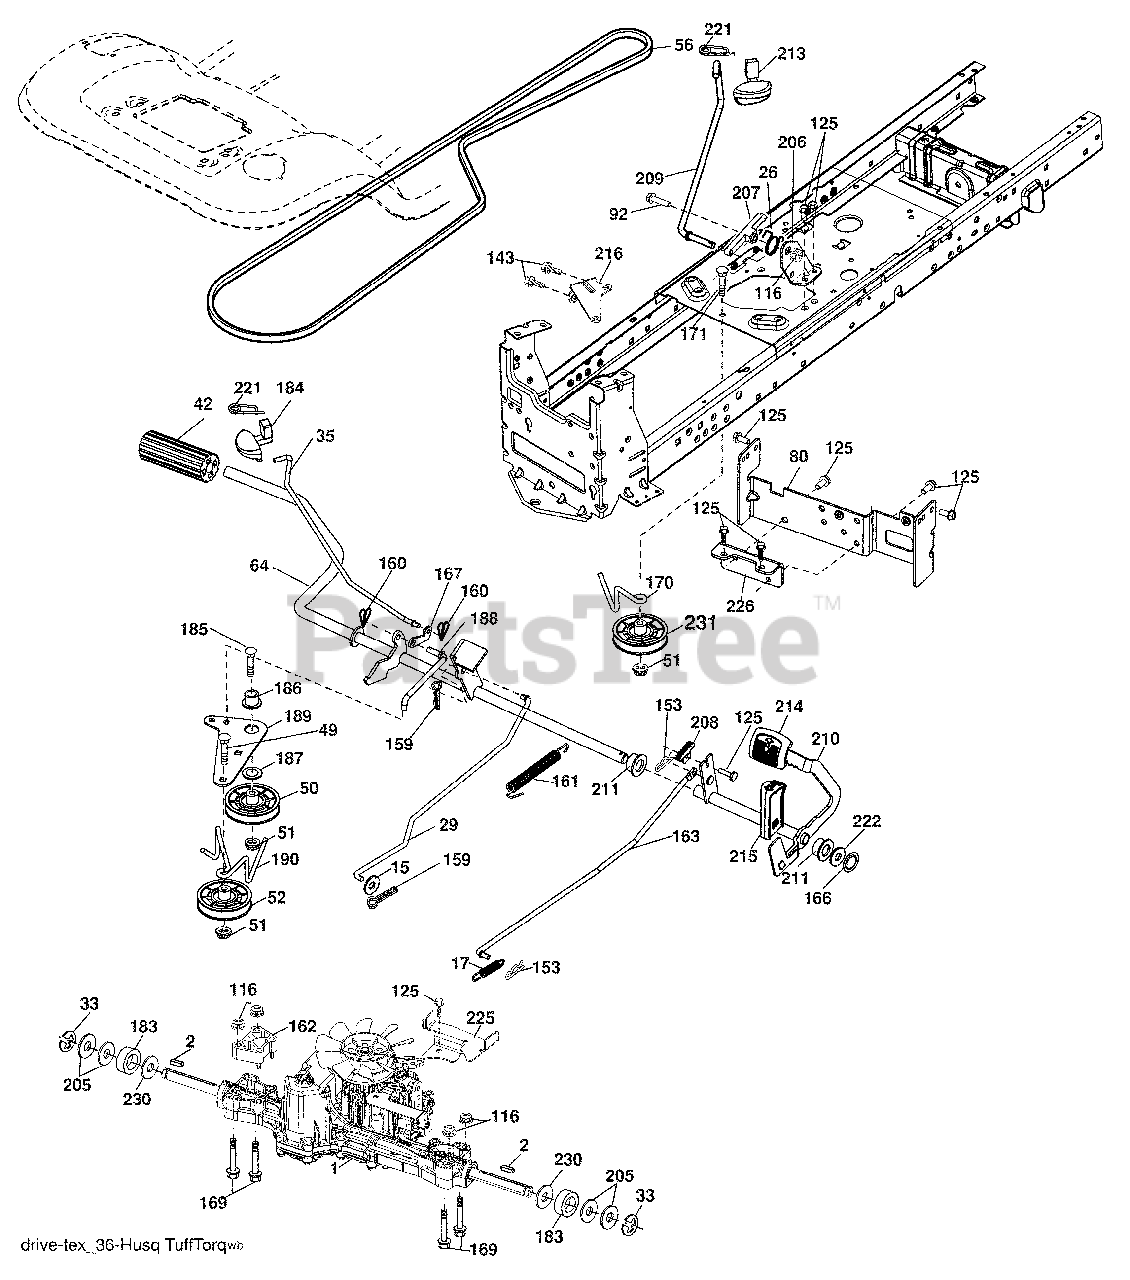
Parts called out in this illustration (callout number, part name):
1	Transaxle, TUFFTORQ K46
2	Key Square
15	Washer 13/32 x 13/16 x 16 Ga.
17	Spring, Brake
26	Spring Return Cruise
29	Rod, Brake
35	Rod, Brake, Park
42	Cover, Foot Pedal
50	Pulley Idler Flat
51	Lock Nut 3/8-16
52	Idler V-Groove 910" Offset
56	V-Belt, Drive
64	Shaft Asm. Pedal Brake Control
80	Strap Torque
92	Bolt Fin Hex 5/16-18 unc x 1.25
116	Nut Lock Hex Flange 5/16-18
125	Screw 5/16-18 x 3/4
143	Screw 5/16-18 x 1/2
153	Retainer Spring
159	Pin Cotter 1/8 x 3/4
160	Retainer Clip
161	Spring, Return, Clutch
162	Spacer Transaxle
163	Rod Pedal Control
166	Nut Push
167	Latch Brake Parking
169	Bolt Hex 5/16-18 x 3.75
170	Keeper Belt Centerspan
171	Bolt
183	Spacer Axle
184	Handle Parking Brake
185	Bolt
186	Spacer Retainer
187	Washer
188	Link Clutch Ground Drive
189	Bellcrank Ground Drive
190	Keeper Bellcrank Ground Drive
205	Washer 25/32 x 1-5/8 16 Ga.
206	Bracket Mount Latch Cruise
207	Latch Control Cruise
208	Gear Sector Control Cruise
209	Rod Control Cruise
210	Rockr Asm. Pedal Control
211	Bearing Nylon
213	Knob control Cruise
214	Pad Pedal Forward
215	Pad Pedal Reverse
216	Bracket Pulley Idler
221	Retainer Spring Clip
222	Washer 21/32 x 1-1/4 10 Ga.
225	Keeper Bolt Transaxle
226	Bracket Mount Torque
230	Washer Hardened
231	Idler V-Groove 1.688" OFFSET
